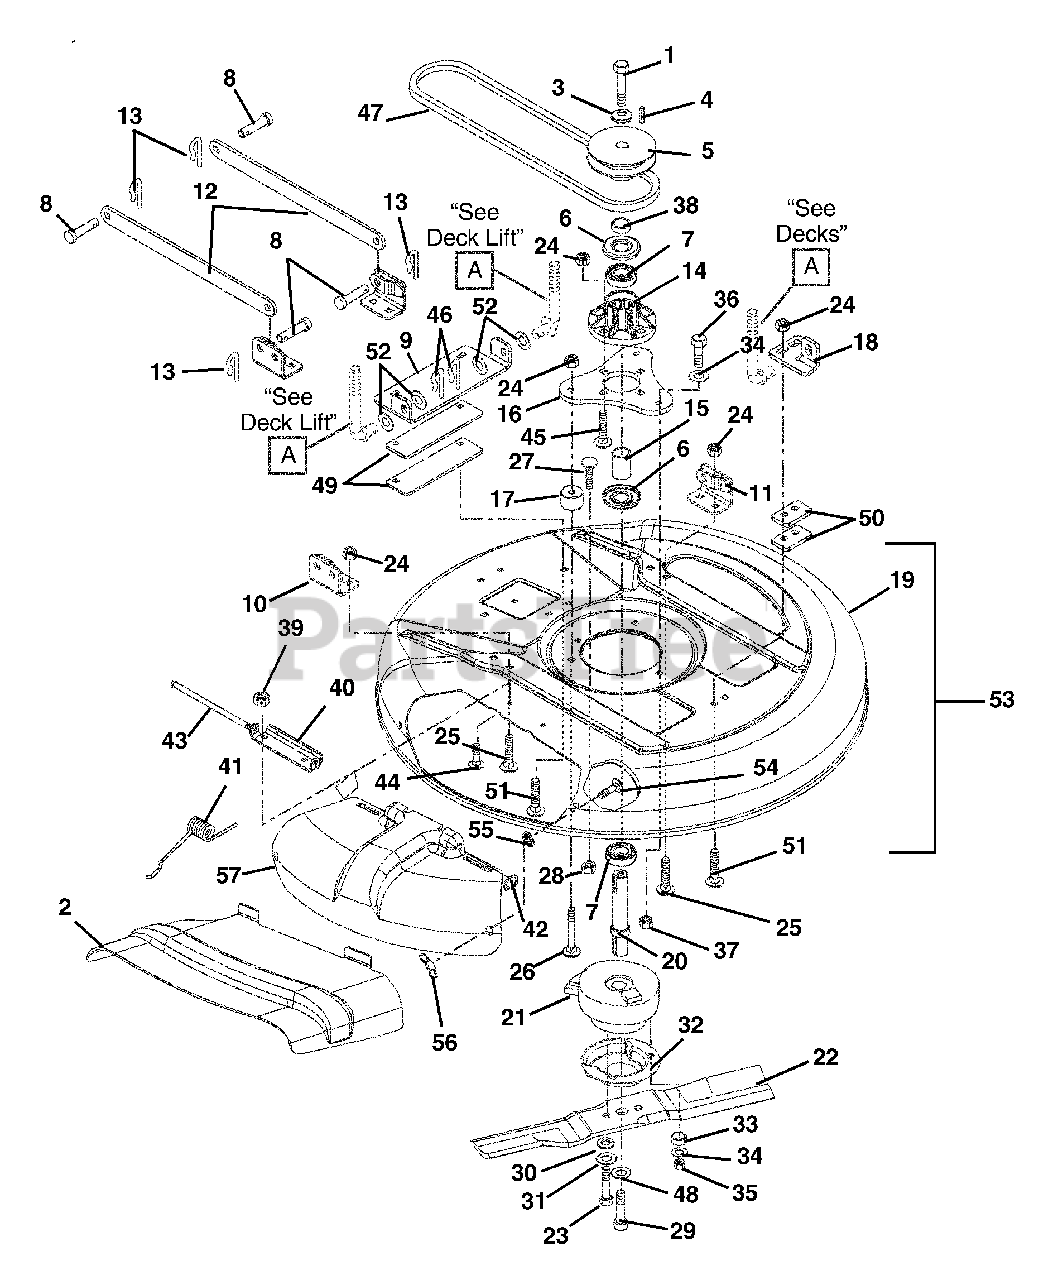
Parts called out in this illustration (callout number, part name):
1	BLT-HEX .38-16X1.00 YZ GR8
2	DISCHARGE CHUTE
3	WASHER, CUPPED SERRATED, .375
4	KEY, SQ .25 X .38 X .25
5	SHEAVE, 4.75 DIA A-SECTION
5	PULLEY, 32" DECK INPUT
6	BEARING SLINGER
7	BRG-BALL 1.0X2.0X.56 (1641)
8	PIN-CLEV .494X1.00 BLKZC
9	BRKT, FRONT LIFT HANGER (32")
10	BRKT, 28" DECK STABILIZER
11	WLDMT-DECK LINK (LH)
12	LINK STABILIZER 32"
13	CLIP, SPRING
14	ASSY-SPINDLE HSG
15	SPACER, 1.001 X 1.25 X 1.76
16	SPINDLE MOUNT PLATE
17	SPACER-MOUNTING PLATE
18	BRKT, FRONT LIFT HANGER (32")
19	DECK, RER/SZ 32"
20	SHAFT, 28" AND 32" INPUT
21	KIT, CLUTCH (1232 RER)
22	BLADE, 32" RER/ZS
23	BLT-HEX M10X1.25X30 CLS 10.9
24	NUT-LK-TOP-FLG .38-16 BLKZC
25	BLT-RDHDSQNK .38-16X.75 G5BZ
26	BLT-RDHDSQNK .38-16X2.25 G5BZ
27	@BLT-RDHDSQNK .31-18X1.50 G5YZ
28	@NUT-SPNLK-FLG .312-18 YWZC
29	SCR-SKN .5-20X1.25 BTNHD
30	WSHR-LK M 10MM YZ
31	WSHR-FL-STL .406X1.00X.188 YWZ
32	SHIELD, DEBRIS
33	BSHG, SPCR .752X.877X.50 BRZ
34	@WSHR-FL-STL.38X.875X.083 YWZC
35	@NUT-LK-NYL .38-16 YWZC
36	BLT-HEX .38-16X3.00 GR5 FTH YZ
37	@NUT-SPNLK-FLG .375-16 YWZC
38	SPACER 1.008X1.377X.509 ST
39	NUT-LK-FLG .250-20 PL BLK
40	BKT, HINGE
41	SPRING, TORSION
42	RG-RTNG-EXT .312X.025
43	PIN, HINGE
44	@BLT-RDHDSQNK .25-20X.75 G5YZ
45	@BLT-RDHDSQNK .38-16X1.25 G5YZ
46	PIN, HAIR, EXT - #16 YWZC
47	V-BELT, HA-WRAPPED
48	WASHER, FLT STL .5X1.75X.187
49	PLATE, 32" REAR HANGER SPACER
50	PLATE, 32" FRONT HANGER SPCR
51	@BLT-RDHDSQNK .38-16X1.25 BKZC
52	WSHR-FL-STL .518X2.0X.105 YWZC
53	KIT, 32" DECK SERVICE ASSY
54	BLT-RDHDSQSHK.31-18X.75 GR2 YW
55	NUT-PUSH .312
56	NUT-NYLK WING .312-18 YWZC
57	MULCH COVER, 32" DECK
